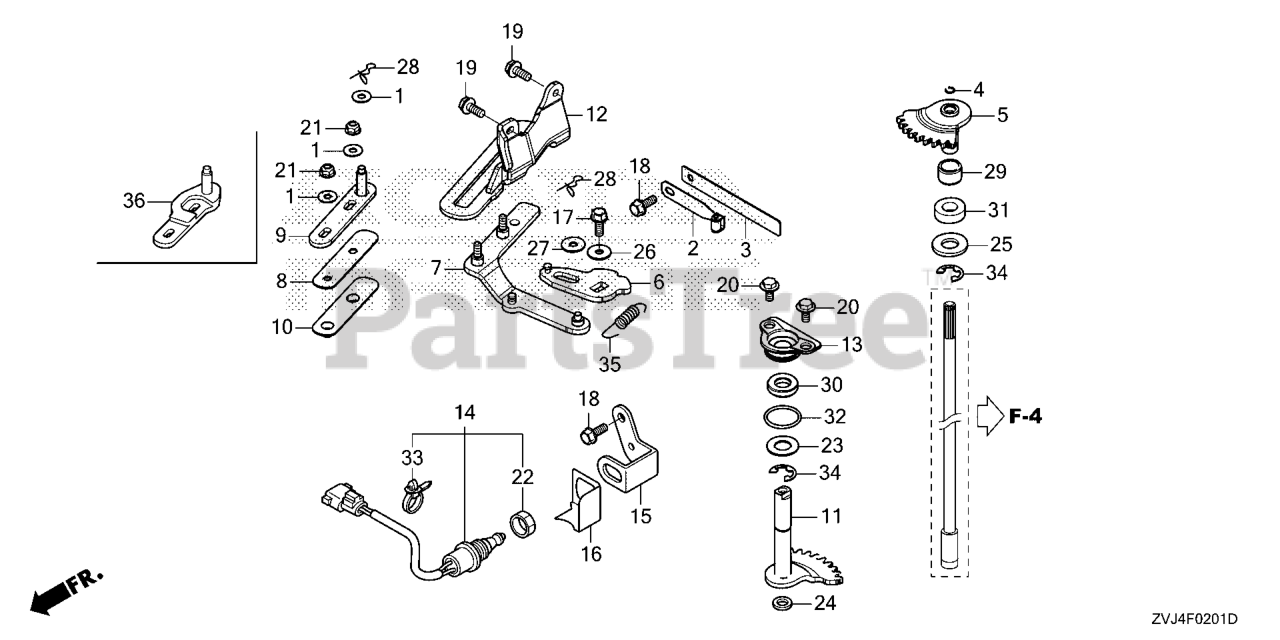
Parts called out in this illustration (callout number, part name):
1	WASHER, PIVOT
2	SPRING, CLICK
3	SPRING, CLICK ASSIST
4	RING, STOPPER
5	SHAFT, SHIFT (A)
6	ARM, SHIFT
7	LINK ASSY., SHIFT
8	PLATE, SHIFT PIVOT
9	ROD, ACTUATOR LINK
10	PIVOT, SHIFT SLIDE
11	SHAFT, SHIFT (B)
12	GUIDE, SHIFT LINK
13	HOLDER, SEAL
14	SWITCH ASSY., NEUTRAL
15	BRACKET, NEUTRAL SWITCH
16	COVER, NEUTRAL SWITCH
17	BOLT, FLANGE (6X16)
18	BOLT, FLANGE (6X14)
19	BOLT, FLANGE (8X20)
20	BOLT, FLANGE (6X11)
21	NUT, SELF-LOCK (6MM)
22	NUT, HEX. (20MM) Use up to Frame SN 1300359.
23	WASHER, THRUST (14MM)
24	WASHER B, THRUST (14MM)
26	WASHER, PLAIN (6MM)
27	WASHER, PLAIN (6MM)
28	PIN, SNAP (6MM)
29	RING (INNER) (15X20X13)
30	OIL SEAL (14X26X6)
31	SEAL, WATER (14X26X8)
32	O-RING (26.9X2.4) (NOK)
33	CLIP, HARNESS BAND (145MM) (BLACK)
34	E-RING (12MM)
35	SPRING, GEARSHIFT ARM
37	ROD KIT, ACTUATOR LINK
